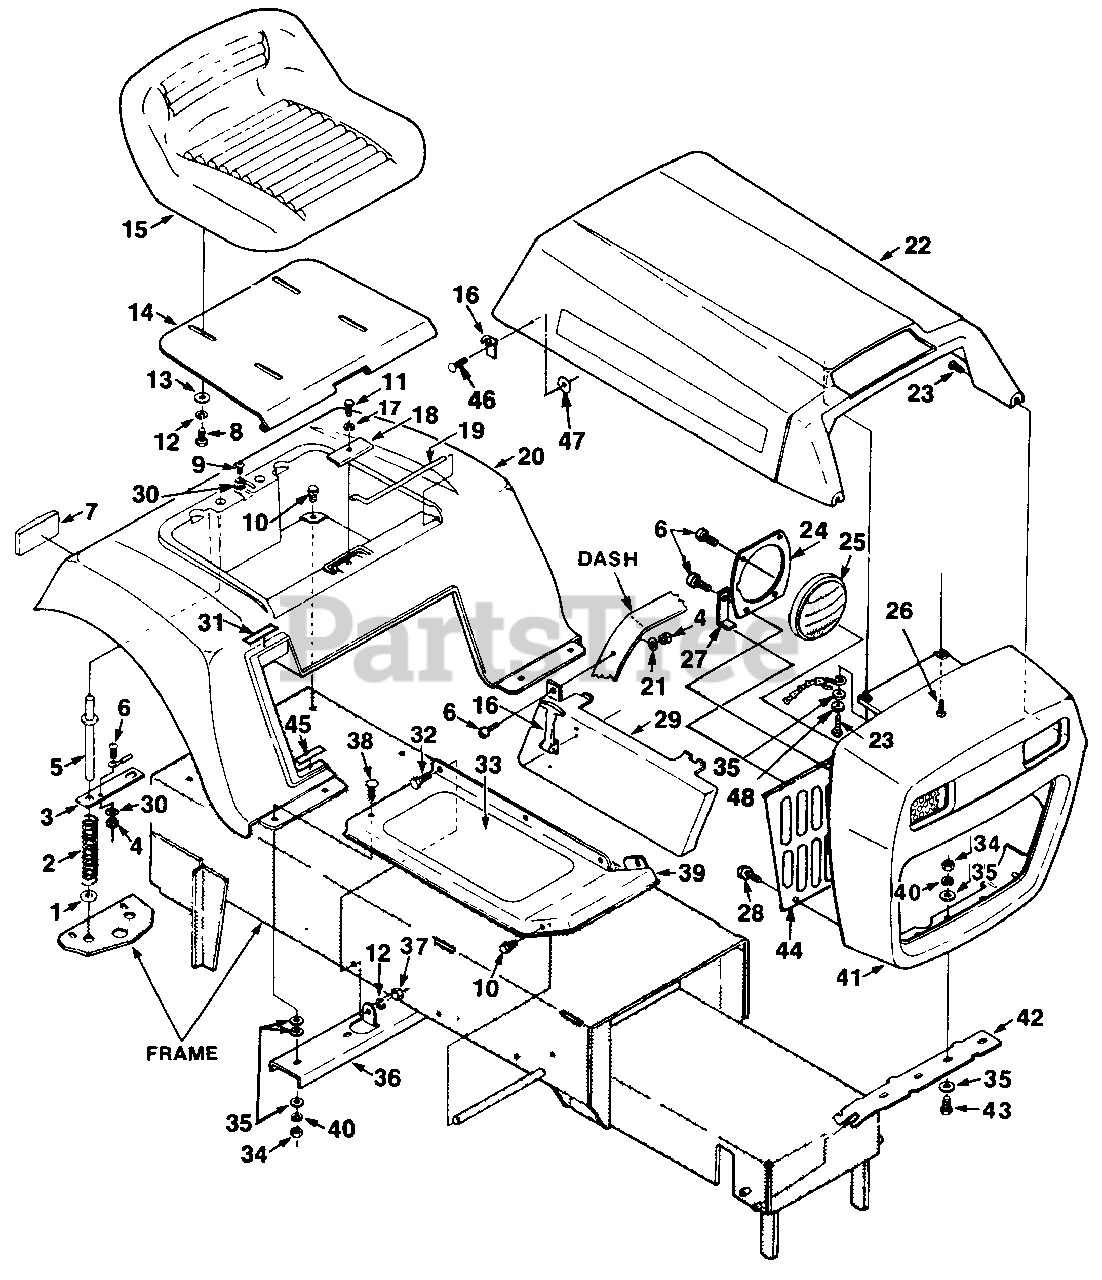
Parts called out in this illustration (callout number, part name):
1	WASHER- Insulation
2	SPRING- Compression
3	CONTACT- Interlock
4	NUT Hex (10-24)
5	PIN- Seat Support
6	SCREW- (10-24 x 3/8")
7	REFLECTOR- Tail light
8	SCREW- Hex hd. (5/16-18 x 5/8")
9	SCREW- (#10 x 1/2")
10	BOLT- (1/4-14 x .44)
11	SCREW- Cap (1/4-20 x 3/4")
12	WASHER- Lock (5/16")
13	WASHER- (5/16")
14	PAN- Seat
17	WASHER- Lock (1/4")
18	BRACKET- Hitch
19	ROD- Hinge
23	SCREW- (1/4 x 14 x 1")
24	RETAINER- Light
25	LIGHT- Head
26	SCREW- Tap hex (1/4-14 x 3/4")
28	SCREW- (1/4-14 x 1/2")
29	PANEL- Side R.H.
30	WASHER- Lock (#10)
31	DECAL- Hi-Lift Pos.
32	BOLT- Hex (5/16-18 x 1")
33	PAD- Footboard
34	NUT- Hex (1/4-20)
35	WASHER- Plain (1/4")
36	BRACKET- Footboard
37	NUT- Hex (5/16-18)
38	BOLT- (1/4-20 x 1")
39	FOOTBOARD, R.H.
40	WASHER- Lock (1/4")
42	HINGE- Grille
43	SCREW- (1/4-20 x 7/8")
44	GRILLE SCREEN
45	DECAL- Lo-Lift Pos.
46	RIVET- Plain
47	WASHER- Flat
48	WASHER- Lock (1/4")
